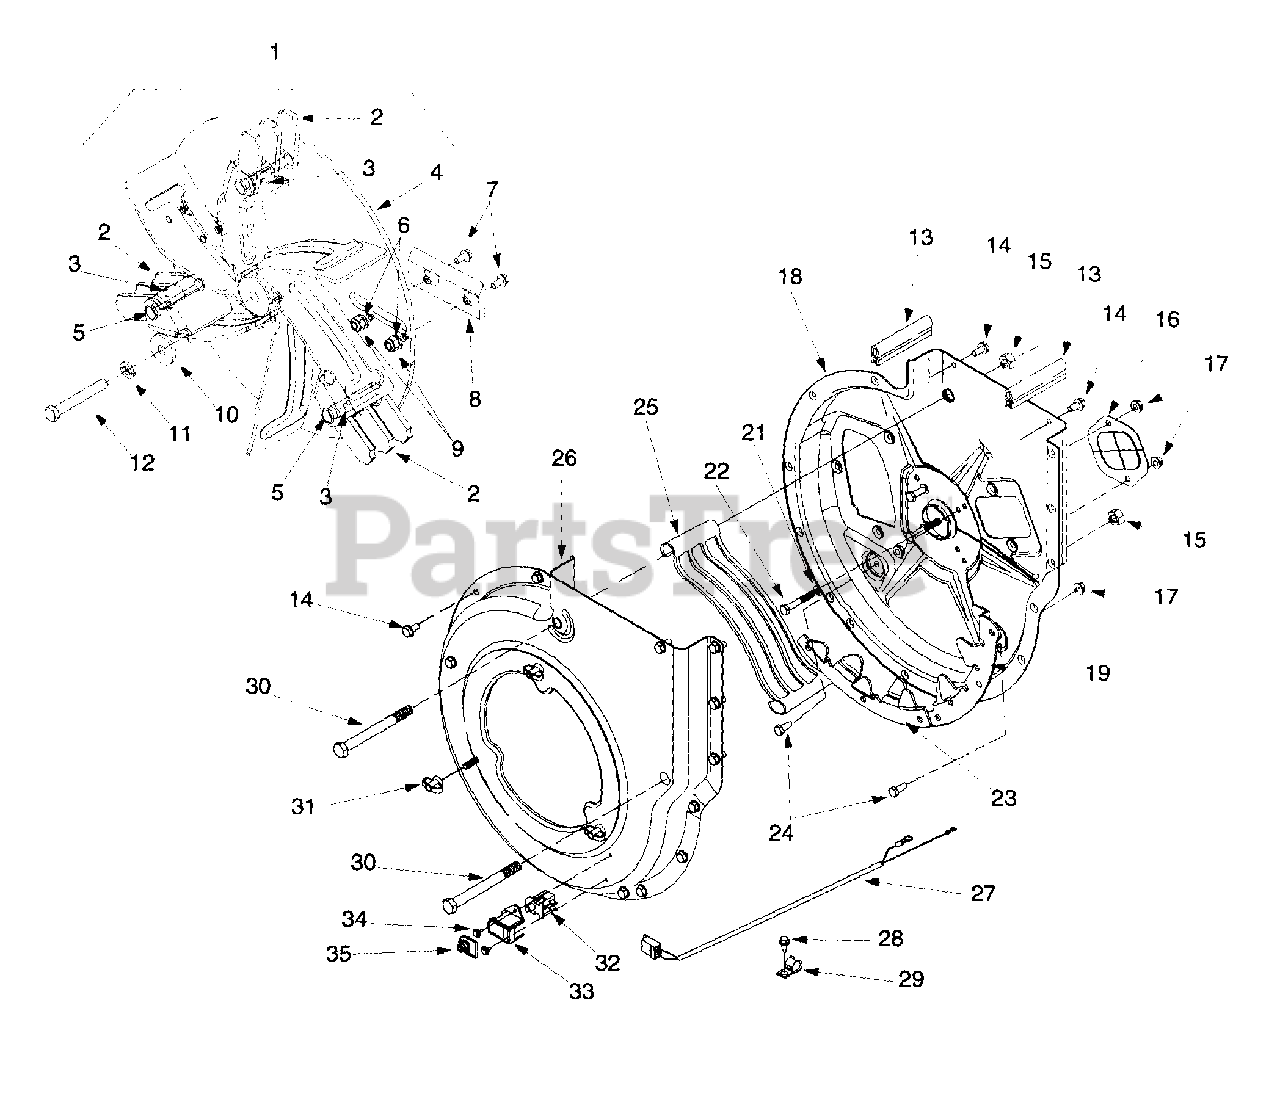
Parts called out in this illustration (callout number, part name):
1	Impeller Ass'y Complete
2	Flail Blade
3	Spiral Pin
4	Impeller Assembly
5	Clevis Pin
6	Lock Washer 5/16
7	Cap Screw 5/16-24 x 1.0
8	Chipper Blade
9	Hex Lock Nut 5/16-24
10	Flat Washer .406 x 1/1/4
11	Lock Washer 3/8
12	Hex Cap Screw 3/8-24 x 2.75
13	Rubber Seal
14	Hex Washer Screw 5/16-18
15	Hex Lock Nut 1/2-13
17	Hex Flange Lock Nut 5/16-18
21	Lock Washer 5/16
22	Hex Cap Screw 5/16-18 x 2
24	Hex Cap Screw 5/16-18 x .75
25	Discharge Screen
27	Wire Harness
28	Hex Washer Screw 1/4-14
29	Clamp
30	Hex Cap Screw 1/2-13 x 5.0
31	Knob 5/16-18
32	Switch
33	Safety Switch Mounting Cover
34	Hex Washer Screw
35	Switch Cover
